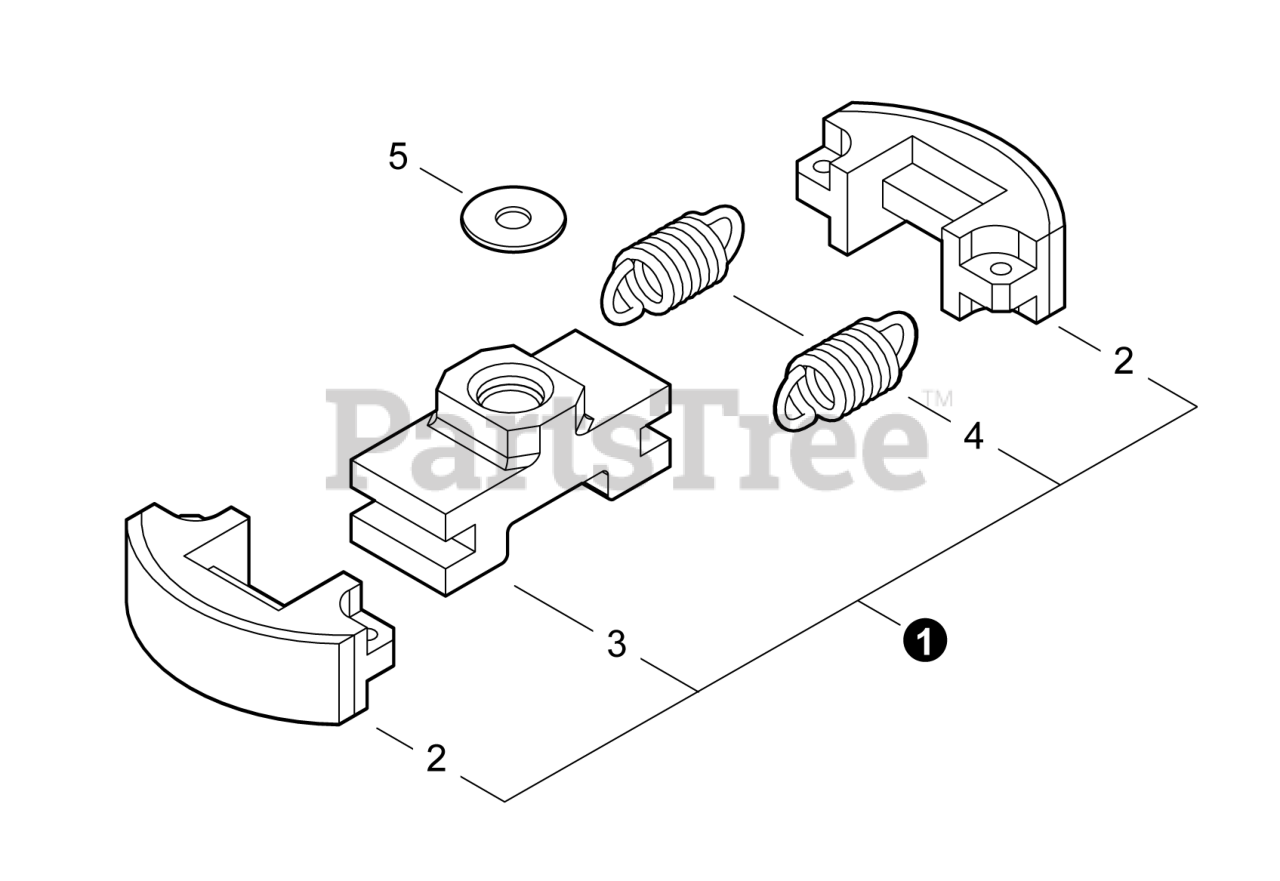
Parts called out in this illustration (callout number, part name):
1	CLUTCH ASSY
2	SHOE, CLUTCH
3	HUB, CLUTCH
4	SPRING, CLUTCH
5	WASHER 8
